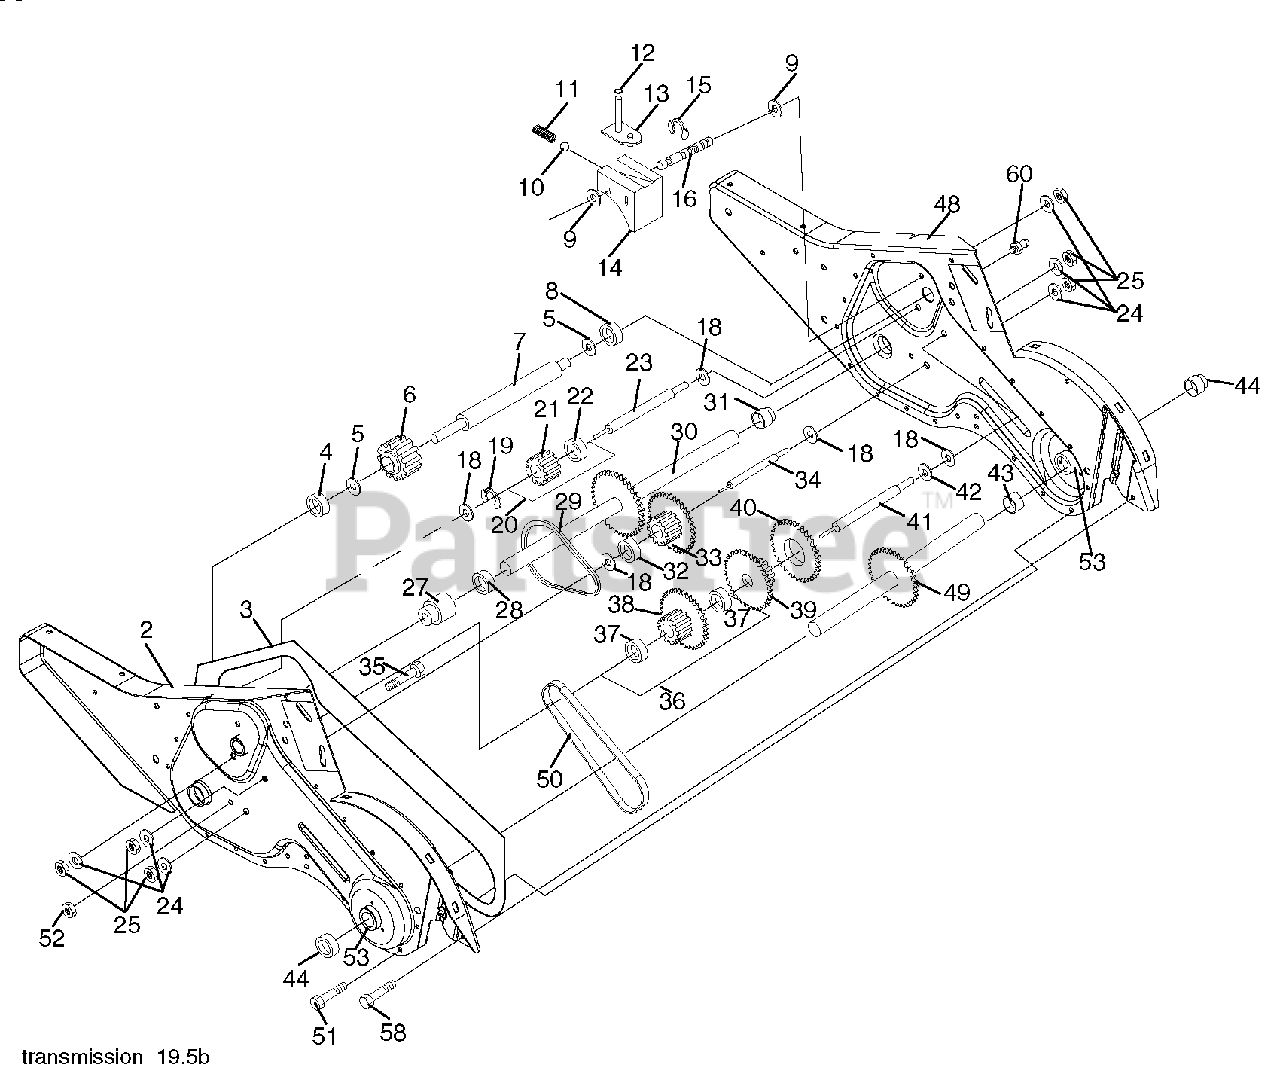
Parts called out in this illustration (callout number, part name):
1	Transmission Assembly
2	Gearcase, L.H. w/Bearing
3	Gasket, Gearcase
4	Bearing, Needle
5	Washer, Thrust 5/8 x 1.10 x 1/32
6	Pinion, Input
7	Shaft, In put
8	Bearing, Needle
9	Washer, Seal
10	Ball, Steel
11	Spring, Shift, Fork
13	Arm, Shift
14	Fork, Shift
15	Ring, Klip
16	Shaft, Shift
19	Ring, Klip
20	Gear, As sem bly, Reverse Idler
21	Gear, Re verse Idler
22	Bearing, Needle
23	Shaft, Re verse Idler
24	Washer, Lock 7/16
25	Nut, Hex 7/16-20
27	Bearing, Shaft, Ground Drive L.H.
28	Spacer 0.765 x 1.125 x 1.23
29	Chain #35-50 Pitch
30	Ground Shaft Assembly
31	Bearing, Shaft, Ground Drive R.H.
32	Spacer 0.70 x 1.00 x 1.150
33	Sprocket and Gear Assembly
34	Shaft, Re duc tion (2nd)
35	Screw, Whiz, Lock 5/16-18 x 3-1/2
36	Sprocket Assembly w/Bearing
37	Bearing, Needle
38	Sprocket, Tine
39	Gear, Clus ter, Red 1st & 2nd
40	Gear, Re verse
41	Shaft, Re duc tion (1st)
42	Washer, Thrust
43	Spacer 1.01 x 1.75 x 0.760
44	Seal Asm, Oil
48	Gearcase, R.H. w/Bearing
49	Shaft, Tine
50	Chain, Roller #50-50 Pitch
51	Screw 1/4-20 x 1/2
52	Nut, Hex 5/16-18
53	Kit, Bearing
58	Bolt Shoulder 1/4-20 unc x .875
60	Fitting Grease
